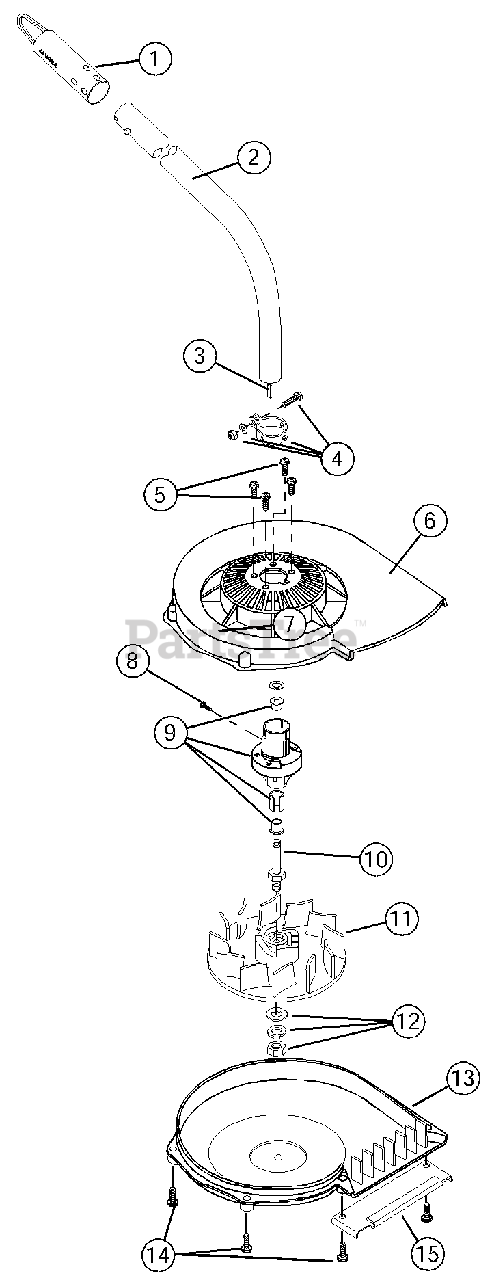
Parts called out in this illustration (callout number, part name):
1	Hanger
2	Drive Shaft Housing Assembly
3	Drive Shaft Assembly
4	Lower Clamp Assembly
5	Mounting Screw Assembly
6	Upper Housing Assembly
7	Palnut
8	Anti-Rotation Screw
9	Bushing Housing Assembly
10	Impeller Shaft
11	Impeller
12	Nut and Washer Assembly
13	Lower Housing Assembly
14	Mounting Screw Assembly
15	Edge Guard
